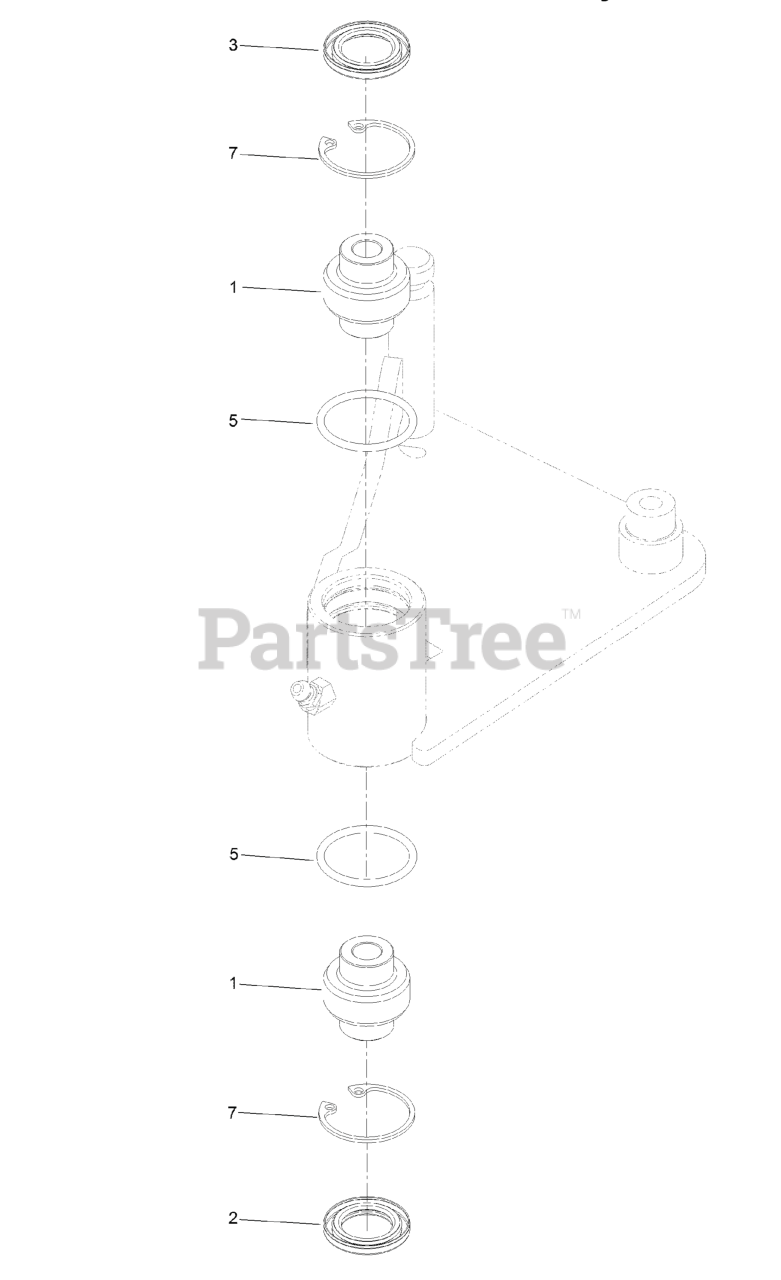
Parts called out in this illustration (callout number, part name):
1	BEARING-SPHERICAL
2	SEAL-LIP, DOUBLE
3	SEAL-LIP, SINGLE
7	RING-SNAP
